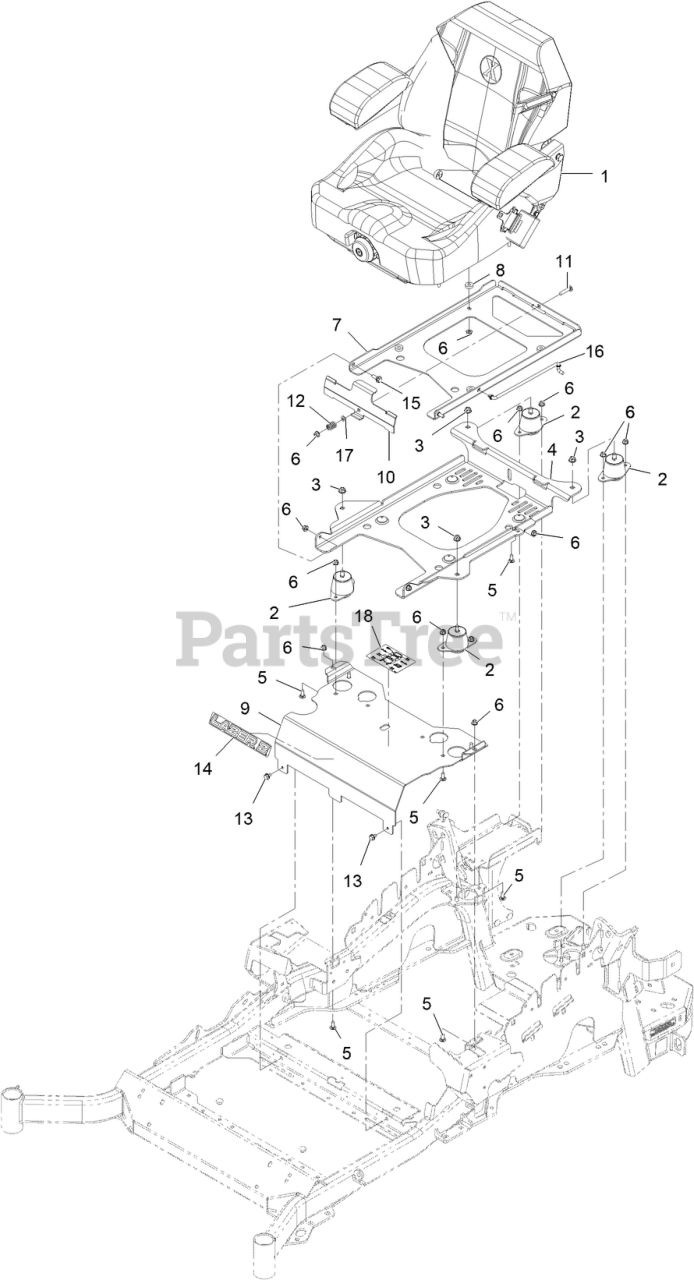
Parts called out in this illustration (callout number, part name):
1	KIT-SUSPENSION SEAT
2	ISOLATOR-SEAT
3	NUT-HF, NI
4	Plate-Tilt Seat Suppport black
5	SCREW-CARR
6	NUT-HF, NI
7	PLATE-FRAME, SEAT
9	Panel-Front, Seat Mount
10	PLATE-LATCH, SEAT
11	BOLT-CARR
12	SPRING-COMPRESSION
14	DECAL, LAZER MODEL
15	SCREW-SHOULDER
16	ROD-PROP
17	WASHER-PLAIN
18	DECAL-SERVICE AID
